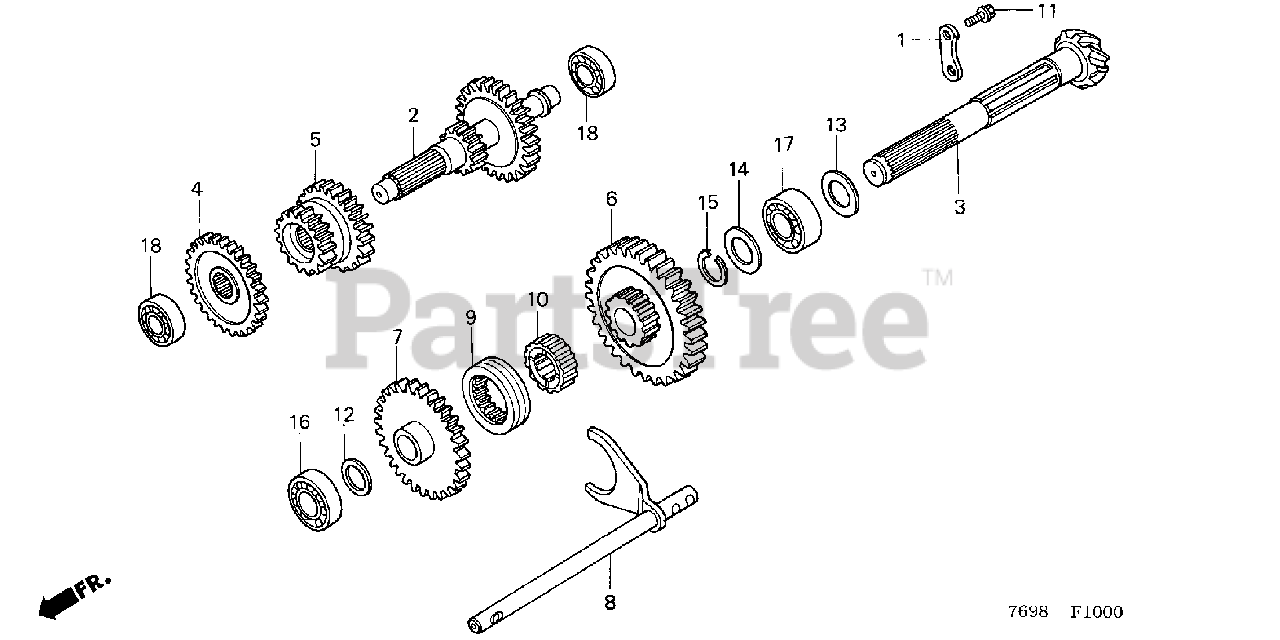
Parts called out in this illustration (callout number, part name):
1	PLATE B, BEARING STOPPER
2	COUNTERSHAFT (LOWER)
3	SHAFT, FINAL
4	GEAR, COUNTERSHAFT THIRD (39T)
5	GEAR, COUNTERSHAFT FOURTH (29T/17T)
6	GEAR, AUXILIARY LOW DRIVEN (39T)
7	GEAR, AUXILIARY DRIVEN HIGH (35T)
8	FORK, AUXILIARY SHIFT
9	SELECTOR, AUXILIARY
10	HUB, AUXILIARY SELECTOR
11	BOLT, FLANGE (8X20)
12	WASHER, THRUST (22X32X1.3) (D)
13	SHIM (25X38X1.25) (A)
13	SHIM (25X38X1.3) (B)
13	SHIM (25X38X1.4) (D)
13	SHIM (25X38X1.45) (E)
13	SHIM (25X38X1.5) (F)
13	SHIM (25X38X1.55) (G)
13	SHIM (25X38X1.6) (H)
13	SHIM (25X38X1.65) (I)
13	SHIM (25X38X1.7) (J)
13	SHIM (25X38X1.75) (K)
14	SHIM, THRUST (25X38X1.3) (B)
14	SHIM, THRUST (25X38X1.35) (C)
14	SHIM, THRUST (25X38X1.4) (D)
14	SHIM, THRUST (25X38X1.45) (E)
14	SHIM, THRUST (25X38X1.5) (F)
14	SHIM, THRUST (25X38X1.55) (G)
14	SHIM, THRUST (25X38X1.6) (H)
14	SHIM, THRUST (25X38X1.65) (I)
14	SHIM, THRUST (25X38X1.7) (J)
14	SHIM, THRUST (25X38X1.75) (K)
15	CIRCLIP (OUTER) (25MM)
16	BEARING, RADIAL BALL (62/22)
17	BEARING, RADIAL BALL (25X52X20.6)
18	BEARING, RADIAL BALL (6203)
